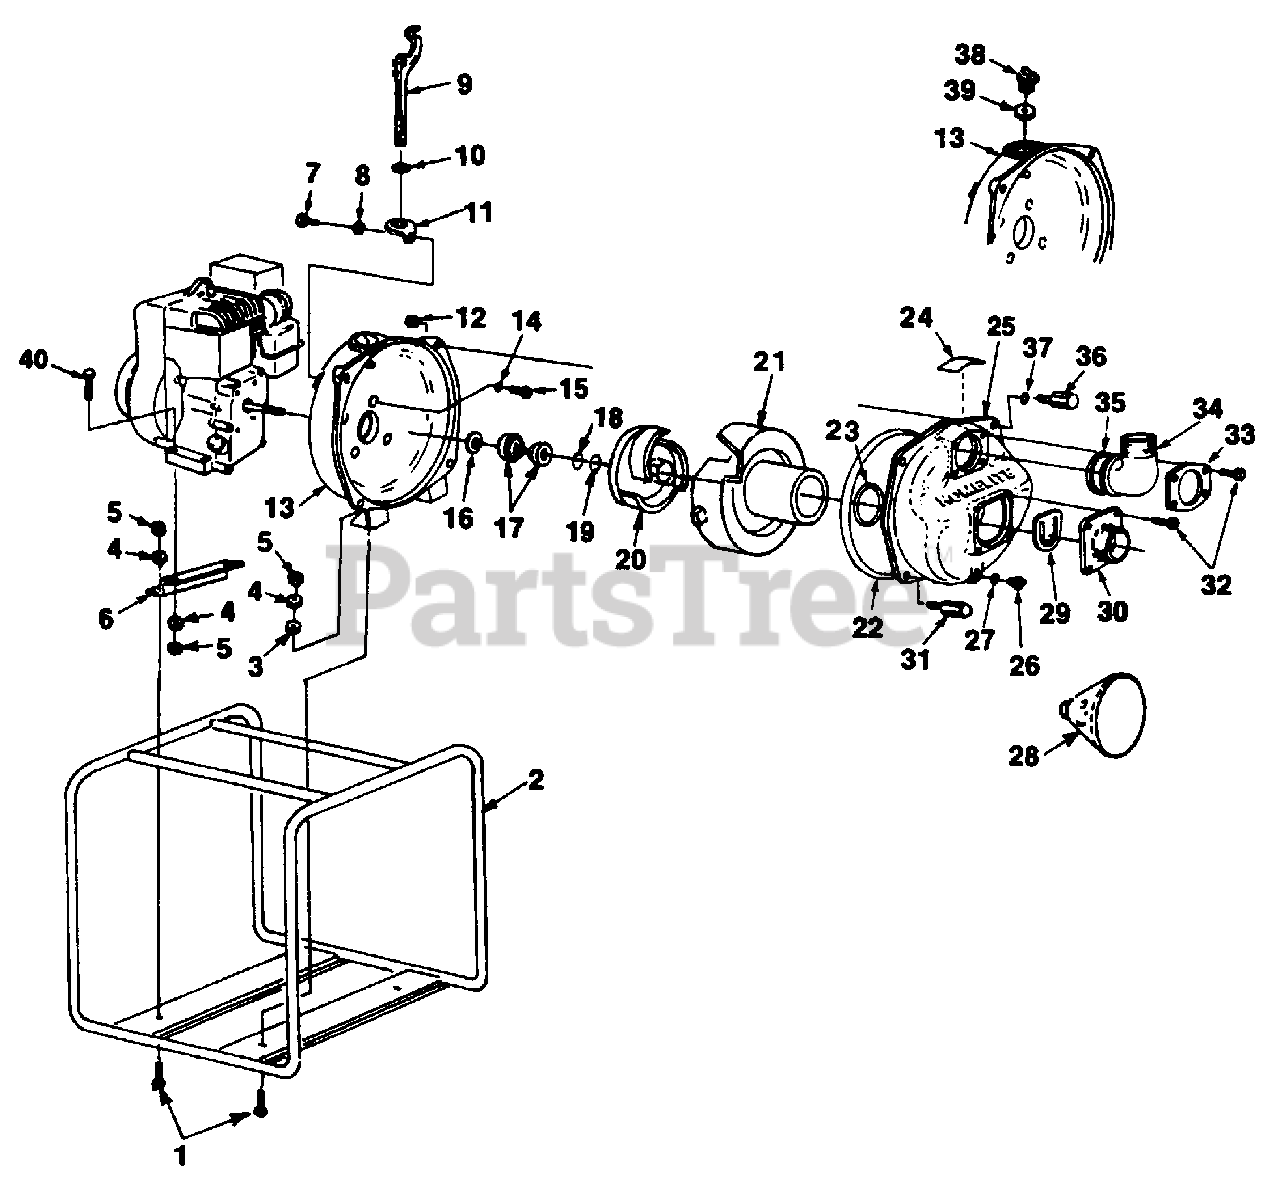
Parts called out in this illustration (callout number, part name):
1	SCREW- Hex hd. (5/16-18 x 1")
2	CAGE- Roll
3	WASHER- Flat (5/16")
4	WASHER- Lock (5/16")
5	NUT- Hex (5/16")
6	SUPPORT- Engine
7	SCREW- Tap hex hd. (1/2-13 x 1 3/4")
8	WASHER- Lock (1/2-13)
9	WRENCH- Spanner (2")
10	GROMMET
11	BRACKET-Spanner wrench
12	NUT- Hex (1/2-13)
13	CASING- Pump
14	WASHER- Sealing
15	SCREW- Mach. Hex
16	"O" RING
17	SEAL- Shaft
18	SHIM (.010")
19	SHIM (.020")
20	IMPELLER, 5 H.P.
21	DIFFUSER, 5 H.P.
22	"O" RING
23	RING- Square
24	LABEL- Warning
25	COVER- Suction
26	CAP- Drain & Filler
27	GASKET- Cap
28	STRAINER (2")
29	VALVE- Check
30	FITTING- Suction (2")
31	BOLT- Casing
32	SCREW- Hex hd. (1/32-18 x 1")
33	CLAMP- Discharge
34	ELBOW- Discharge (2")
35	"O" RING
36	BOLT- Casing
37	WASHER- Lock (1/2")
38	PLUG- Filler
39	GASKET- Wing nut
40	SCREW- Cap hex hd. (1/32-18 x 1 1/2")
